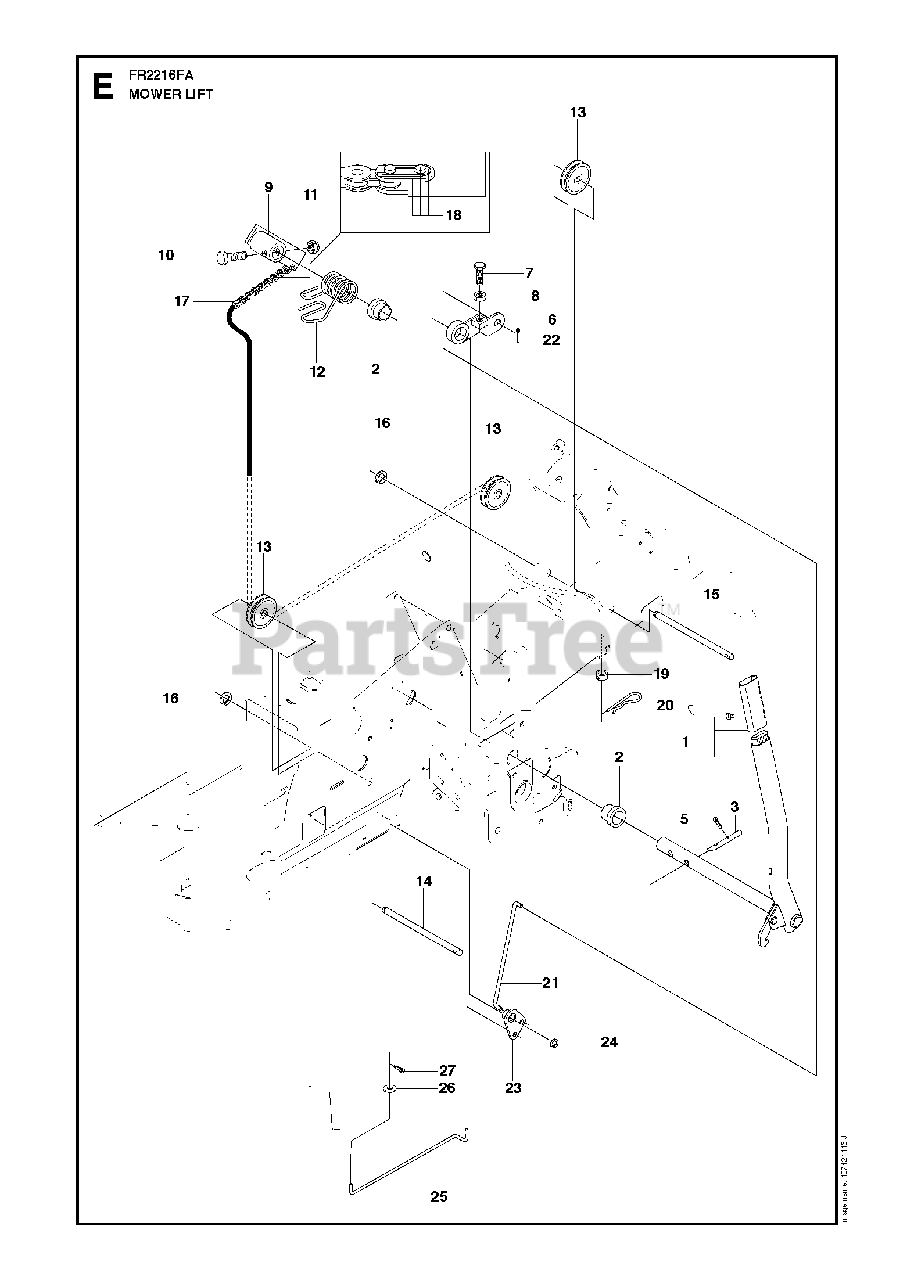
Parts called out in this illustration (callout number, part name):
1	LIFTING LEVER ASSY
2	BUSH
5	SPLIT PIN
6	LEVER CLUTCH
9	LIFTING ARM
16	LOCK RING
21	CONNECTION ROD
22	SPLIT PIN
24	RETAINING RING
25	CONNECTION ROD
27	SPLIT PIN
